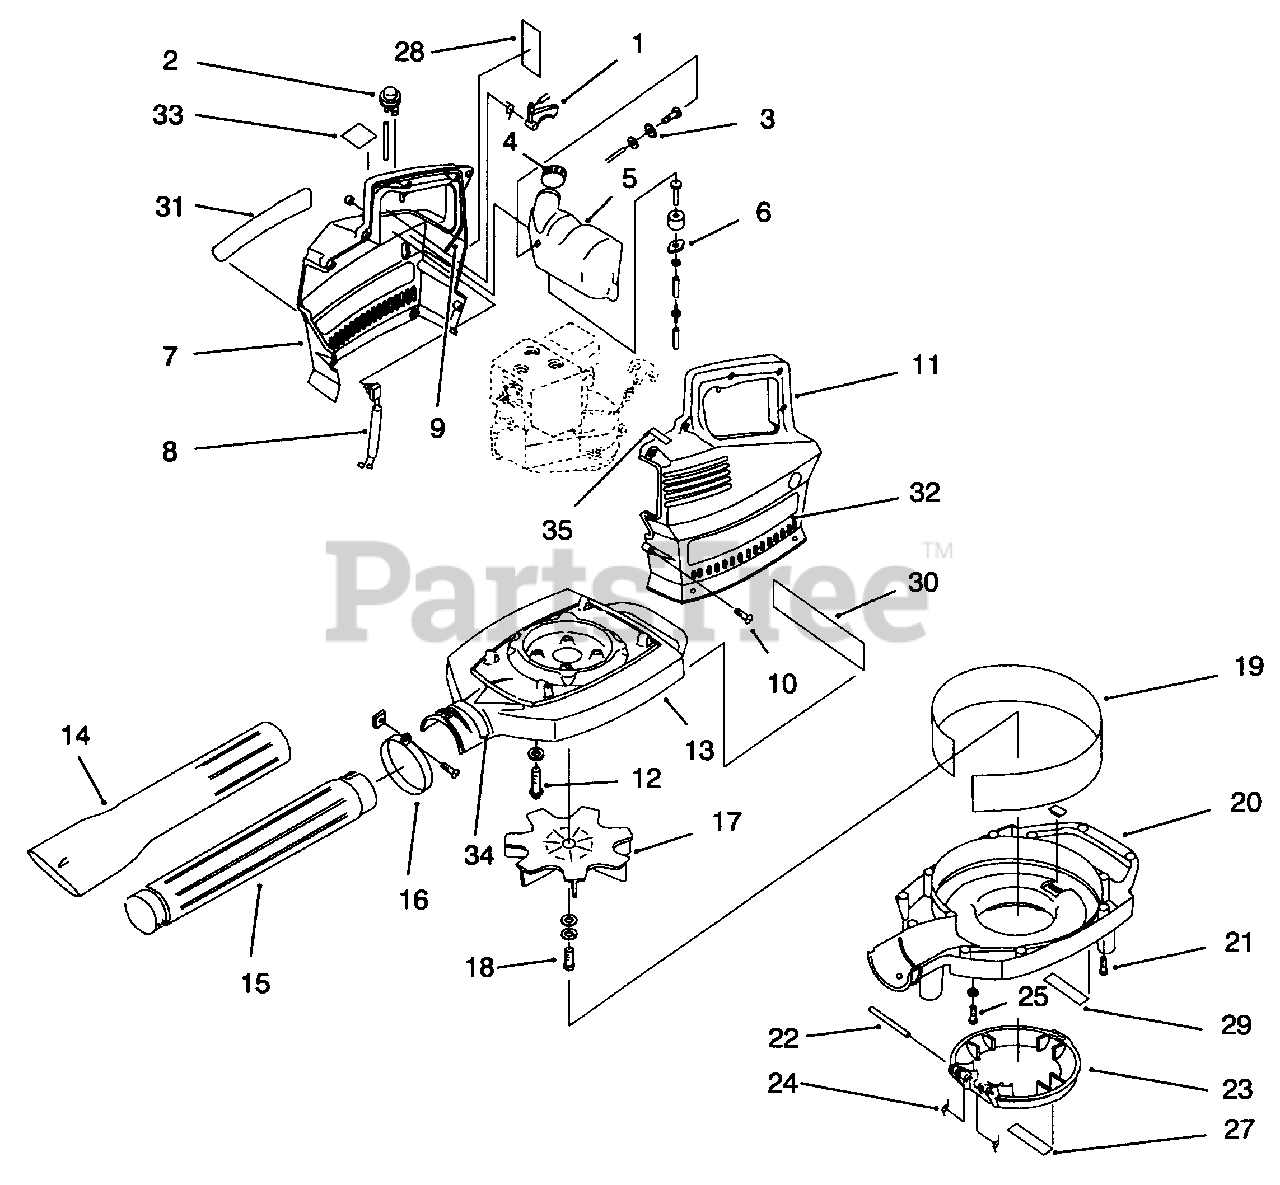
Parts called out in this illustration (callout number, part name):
1	Trigger Asm.
2	ASM-PRIMER BULB & HOSE
3	ASSEMBLY - RETURN LINE
4	FUEL TANK CAP
5	Complete Fuel Tank Asm. (Incl. Ref. #3, 4 and 6)
6	Fuel Line Asm.
7	COVER - RH ENGINE
8	ASM - SWITCH & LEAD
9	ASM-THROTTLE WIRE & HSG
10	SCREW - MOUNTING
11	COVER - LH ENGINE
12	ASSEMBLY - MOUNTING SCREW
13	HOUSING - UPPER BLOWER
14	TUBE - BLOWER W/NOZZLE
15	TUBE - BLOWER
16	ASSEMBLY - CLAMP
17	IMPELLER
18	ASSEMBLY - MOUNTING BOLT
19	SHIELD - IMPACT
20	HOUSING - LOWER BLOWER
21	SCREW - MOUNTING
22	SHAFT - HINGE
23	COVER - INTAKE
24	SPRING SET
25	ASSEMBLY - MOUNTING SCREW
27	DECAL - WARNING
28	Spacer
29	DECAL - PUSH TAB
30	Decal-Fuel & Oil Mix
31	DECAL - RH TORO
32	Decal-Toro L.H.
33	DECAL - PRIME
34	Decal-Safety Symbol
35	Decal-Warning
